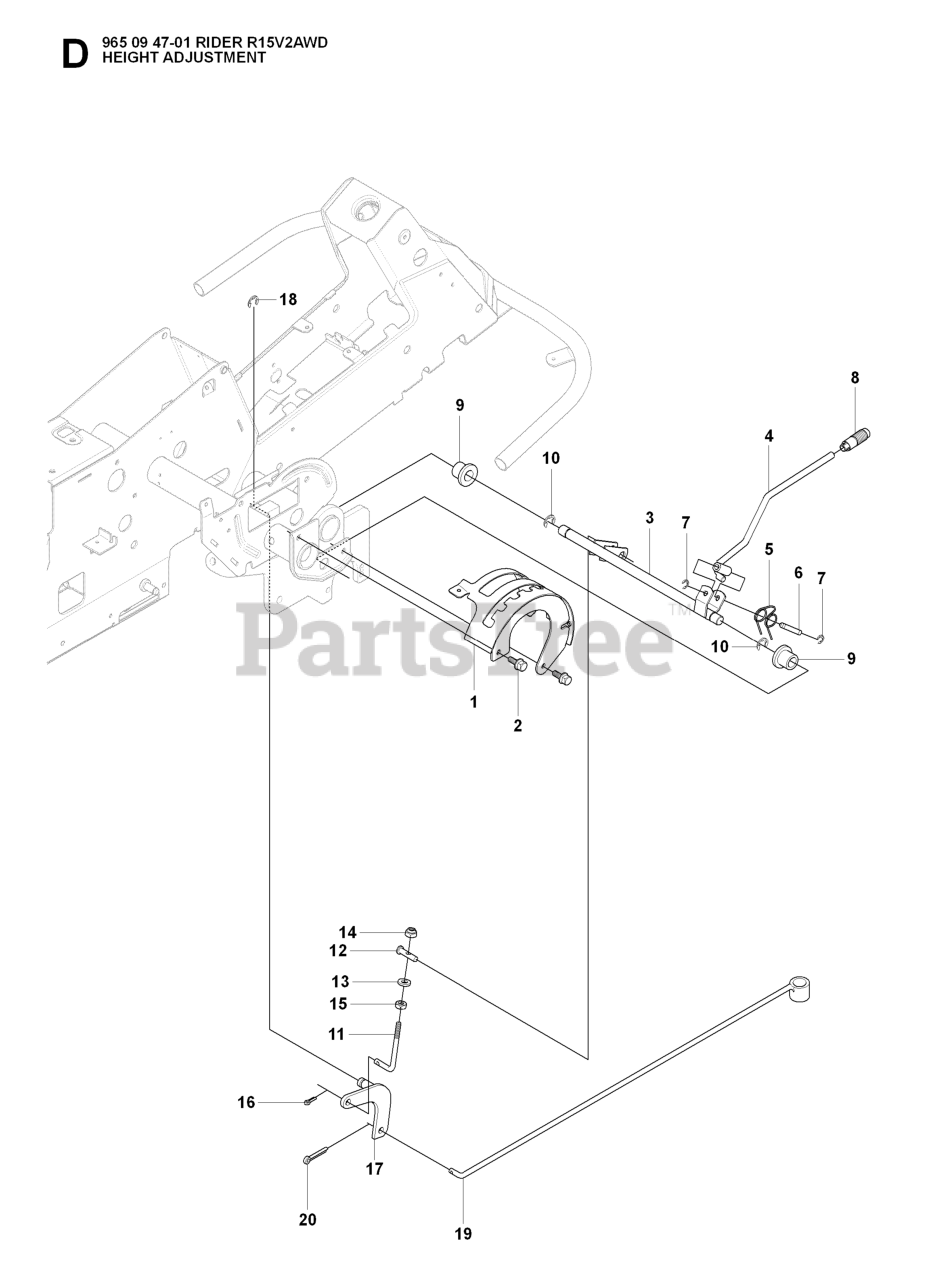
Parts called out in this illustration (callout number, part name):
1	CONTROL PLATE
3	HEIGHT ADJUSTER
4	HEIGHT ADJUSTER
5	HAIR PIN SPRING
8	GEAR STICK KNOB
9	BUSHING
13	WASHER
14	LOCKNUT M8
15	NUT
18	RETAINING RING
19	CLUTCH ROD
